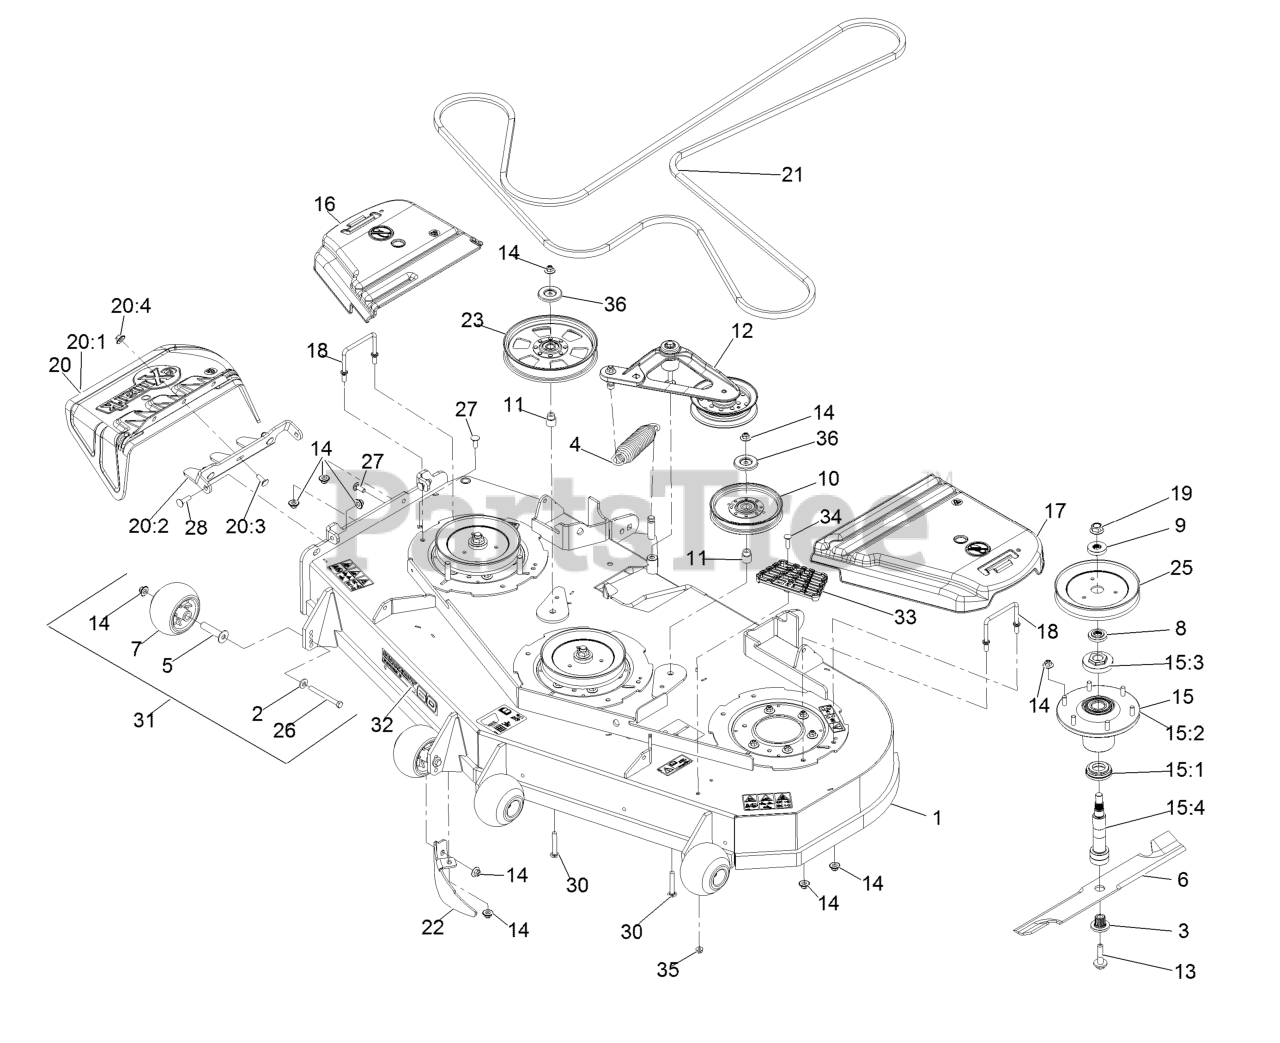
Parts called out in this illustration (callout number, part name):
1	Deck ASM,W/Decals 60
2	Washer-Spring Disc 3/8
3	Bushing, Splined
4	Spring-Extension
5	Axle, Roller
6	Blade, Solid
6	Blade, Low Lift
6	Blade, Mulching
6	Blade, Notched
6	Blade-Extreme 2, 20.50"
7	Roller-Anti-Scalp
8	Spacer, Splined Stepped
9	Spacer, Splined
10	Idler-Pulley
11	Bushing, Idler
12	Deck Idler ASM
13	Screw-Sems 1/2-20 X 2.19
14	Nut-Nyloc 3/8-16 Flg
15	ASM,Spindle Housing
15:1	Guard, Bottom
15:2	Asm, Cutter Housing
15:3	Nut, Spindle 7/8-14
15:4	Spindle,Double Spline
16	Cover-Belt, RH
17	Cover-Belt, LH
18	Wireform-Cover
19	Nut-Flange 5/8-18 Centerlock
20	ASM,Discharge Chute
20:1	Chute, Discharge
20:2	Bracket,Discharge Chute
20:3	Bolt-Carriage 3/8-16 X 1
20:4	Nut-Nyloc 3/8-16 Flg
21	Belt,V-5V-198.75
22	Dogleg - Lz60
23	Pulley-Idler, Flat
25	Sheave,Blade Drive 7.25
26	Screw-HH 3/8-16 X 3 3/4 GR 8
27	Bolt-Carriage 3/8-16 X 1
28	Bolt-Carriage 3/8-16 X 1 1/4
30	Bolt-Carriage 3/8-16 X 2 1/2
31	Kit, Anti-Scalp Roller
32	Decal, 606
33	Step-Deck
34	Bolt-Carriage 5/16-18 X 1 1/4
35	Nut-Nyloc 5/16-18 Flg
36	Shield-Dust
